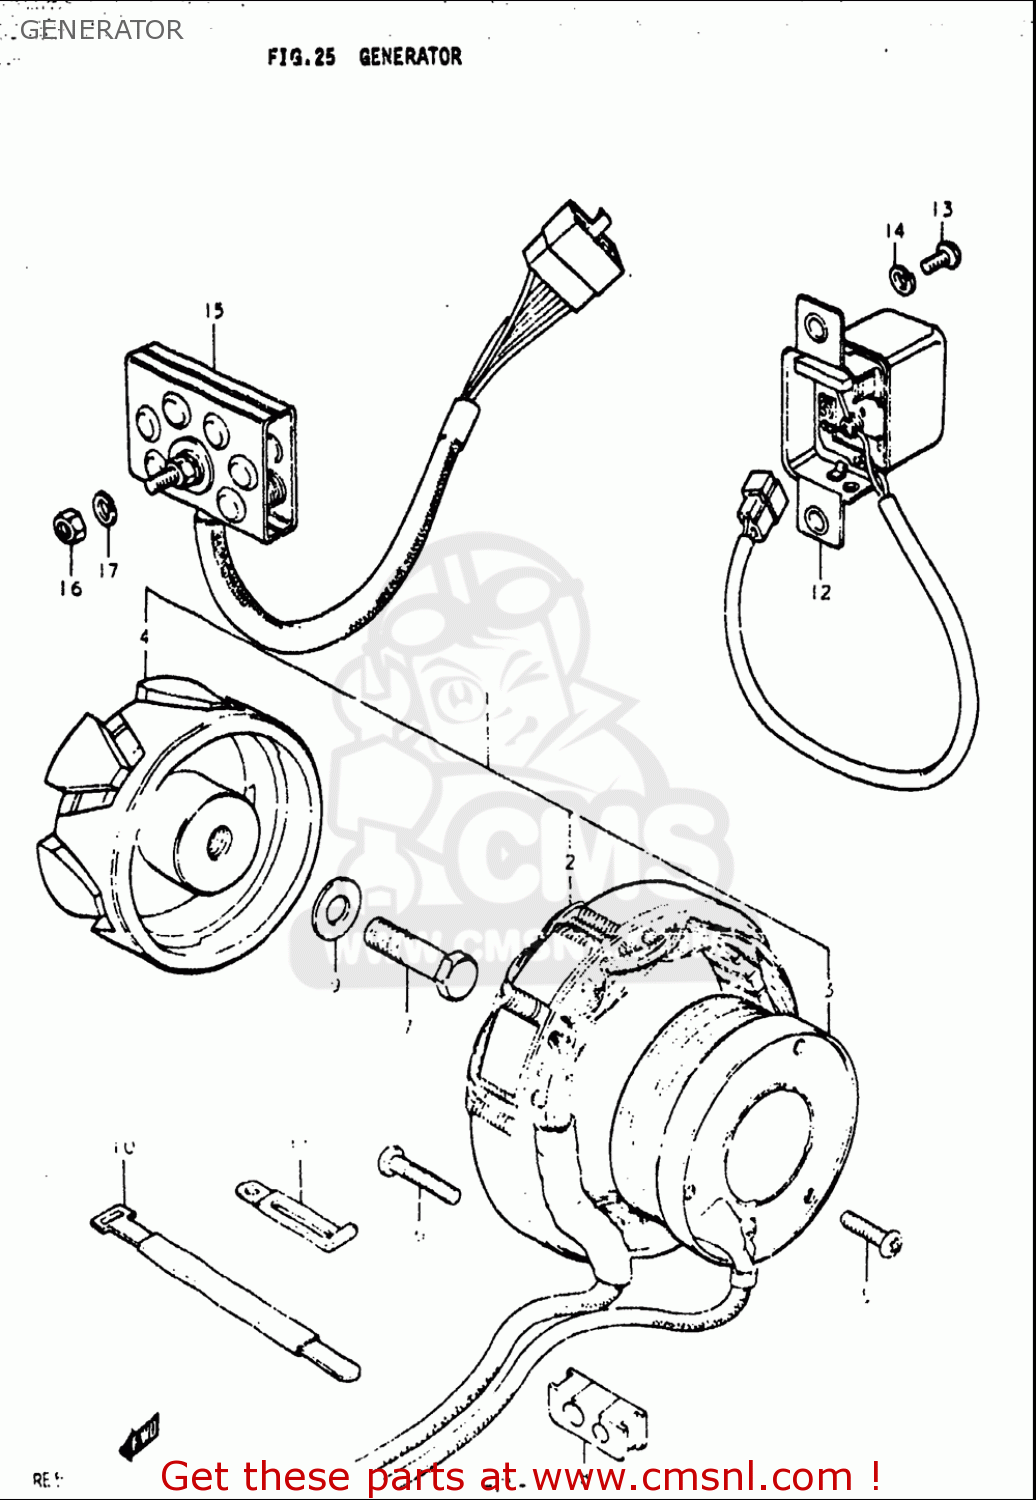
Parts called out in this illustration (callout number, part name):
5	SCREW
6	SCREW
7	BOLT
9	WASHER
10	CLAMP
11	CLAMP(L:65)
12	REGULATOR ASSY,VOLTAGE
13	BOLT
14	WASHER,LOCK
15	RECTIFIER ASSY
16	NUT
17	WASHER,LOCK
